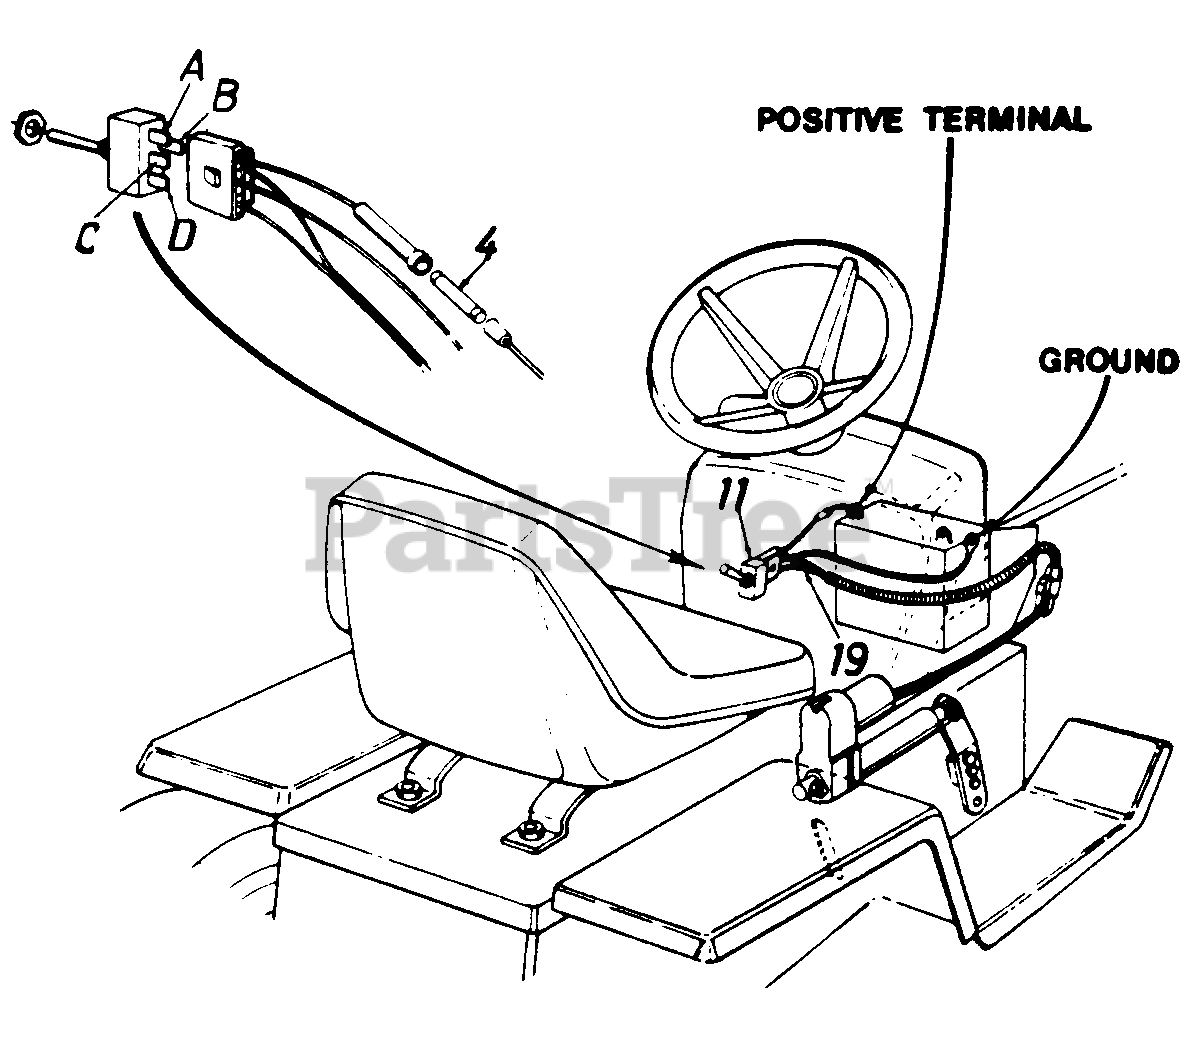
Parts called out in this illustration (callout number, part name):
4	Fuse 30 AMP
11	Toggle Switch
19	Wire Harness
A	Blue Wire Connects to Positive Terminal on Battery
B	Yellow Wire Connects to Actuator
C	Black Wire Ground Wire -to Frame
D	Red Wire Connects to Actuator
